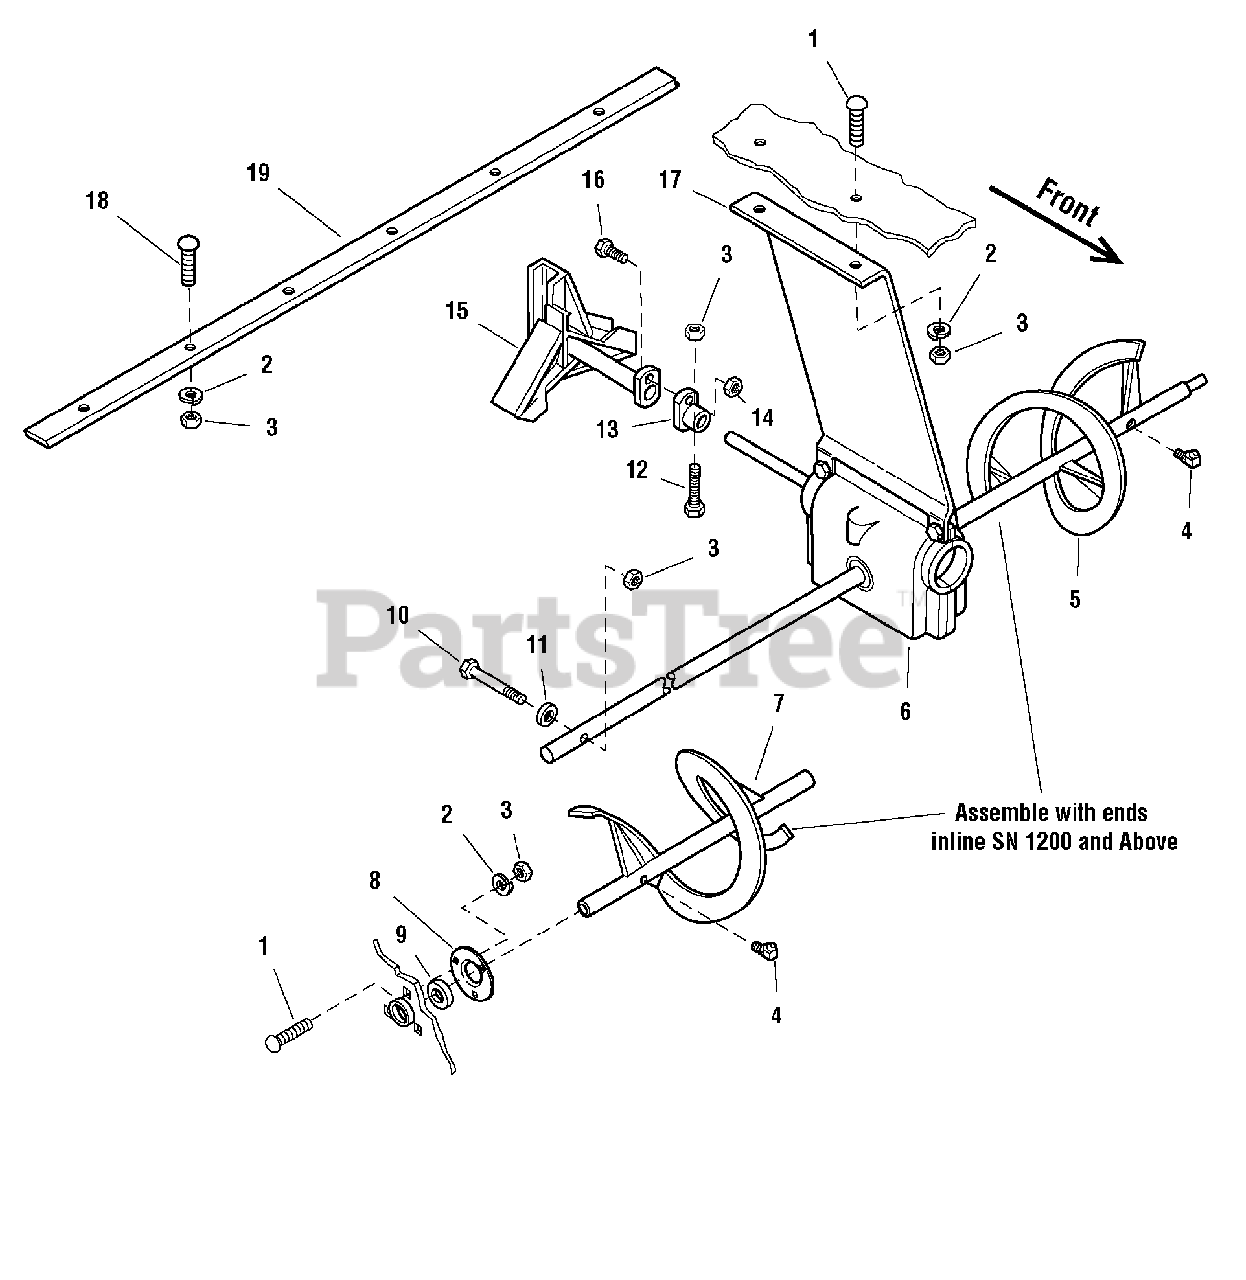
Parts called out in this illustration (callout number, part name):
1	CARRIAGE BOLT, 3/8-16 x 3/4
2	LOCKWASHER, 5/16
3	NUT, HEX, 5/16-18
4	FITTING, Lube
5	AUGER, ASSEMBLY LH
6	GEAR BOX & SHAFT ASSEMBLY, (See Gearbox Mounting & Shaft Group)
7	AUGER, ASSEMBLY RH
8	FLANGE, Bearing, W/Grease Fitting
9	BEARING, Cartridge
10	CAPSCREW, Hex Head, 5/16-18 x 2-1/2
11	WASHER
12	CAPSCREW, Hex Head 5/16-18 x 2 G5
13	PLATE & TUBE ASSEMBLY
14	NUT, Hex, 1/4-20
15	IMPELLER ASSEMBLY
16	CAPSCREW, Hex Head, 1/4-20 x 1
17	SUPPORT
18	CARRIAGE BOLT, 5/16-18 x 1
19	CUTTING EDGE, Scraper
